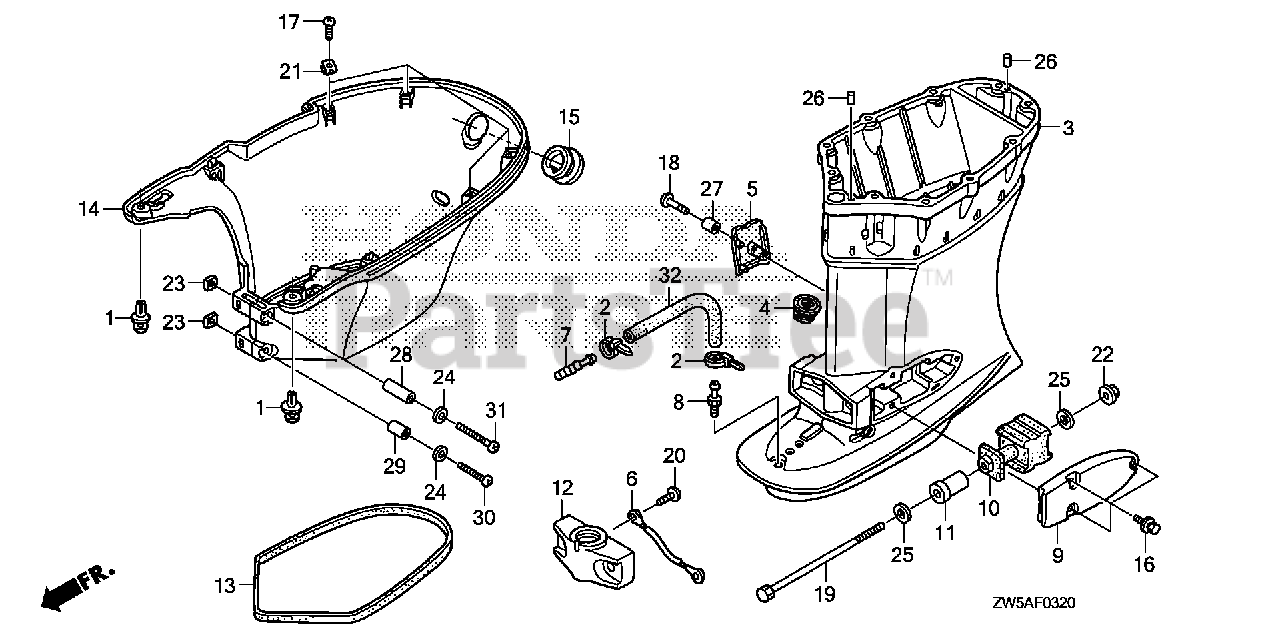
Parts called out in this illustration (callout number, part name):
1	CLIP, FUEL PIPE (BLACK)
2	BAND, WIRE
3	CASE, EXTENSION *NH282MU* (L) (OYSTER SILVER METALLIC-U)
4	RUBBER, DRAIN PLUG
5	COVER, DRAIN PLUG *NH282MU* (OYSTER SILVER METALLIC-U)
6	WIRE, LEAD (1.5X116MM)
7	END, NIPPLE
8	NIPPLE, SENSOR
9	HOUSING, MOUNTING (LOWER) *NH282MU* (OYSTER SILVER METALLIC-U)
10	RUBBER, MOUNT (LOWER)
11	COLLAR, MOUNTING (LOWER)
12	HOUSING, CENTER MOUNTING (LOWER) *NH282MU* (OYSTER SILVER METALLIC-U)
13	SEAL B, COVER (LOWER)
14	COVER (LOWER) *NH282MU* (OYSTER SILVER METALLIC-U)
15	GROMMET, COVER (LOWER)
15	SEAL B, COVER (LOWER)
16	BOLT-WASHER (8X30)
17	SCREW, SPECIAL (6X14)
18	SCREW, SPECIAL (6X35)
19	BOLT, HEX. (12X232)
20	SCREW, PAN (6X8)
22	NUT, FLANGE (12MM)
23	NUT, PLATE (5MM)
24	WASHER, PLAIN (5MM)
25	WASHER, PLAIN (12MM)
26	PIN, DOWEL (6X10)
27	COLLAR, DISTANCE (6X10.5X25)
28	COLLAR, DISTANCE (5X7X38)
29	COLLAR, DISTANCE (5X7X23)
30	SCREW, PAN (5X30)
31	SCREW, PAN (5X45)
32	BULK HOSE, VACUUM (5X3000) (5X200)
